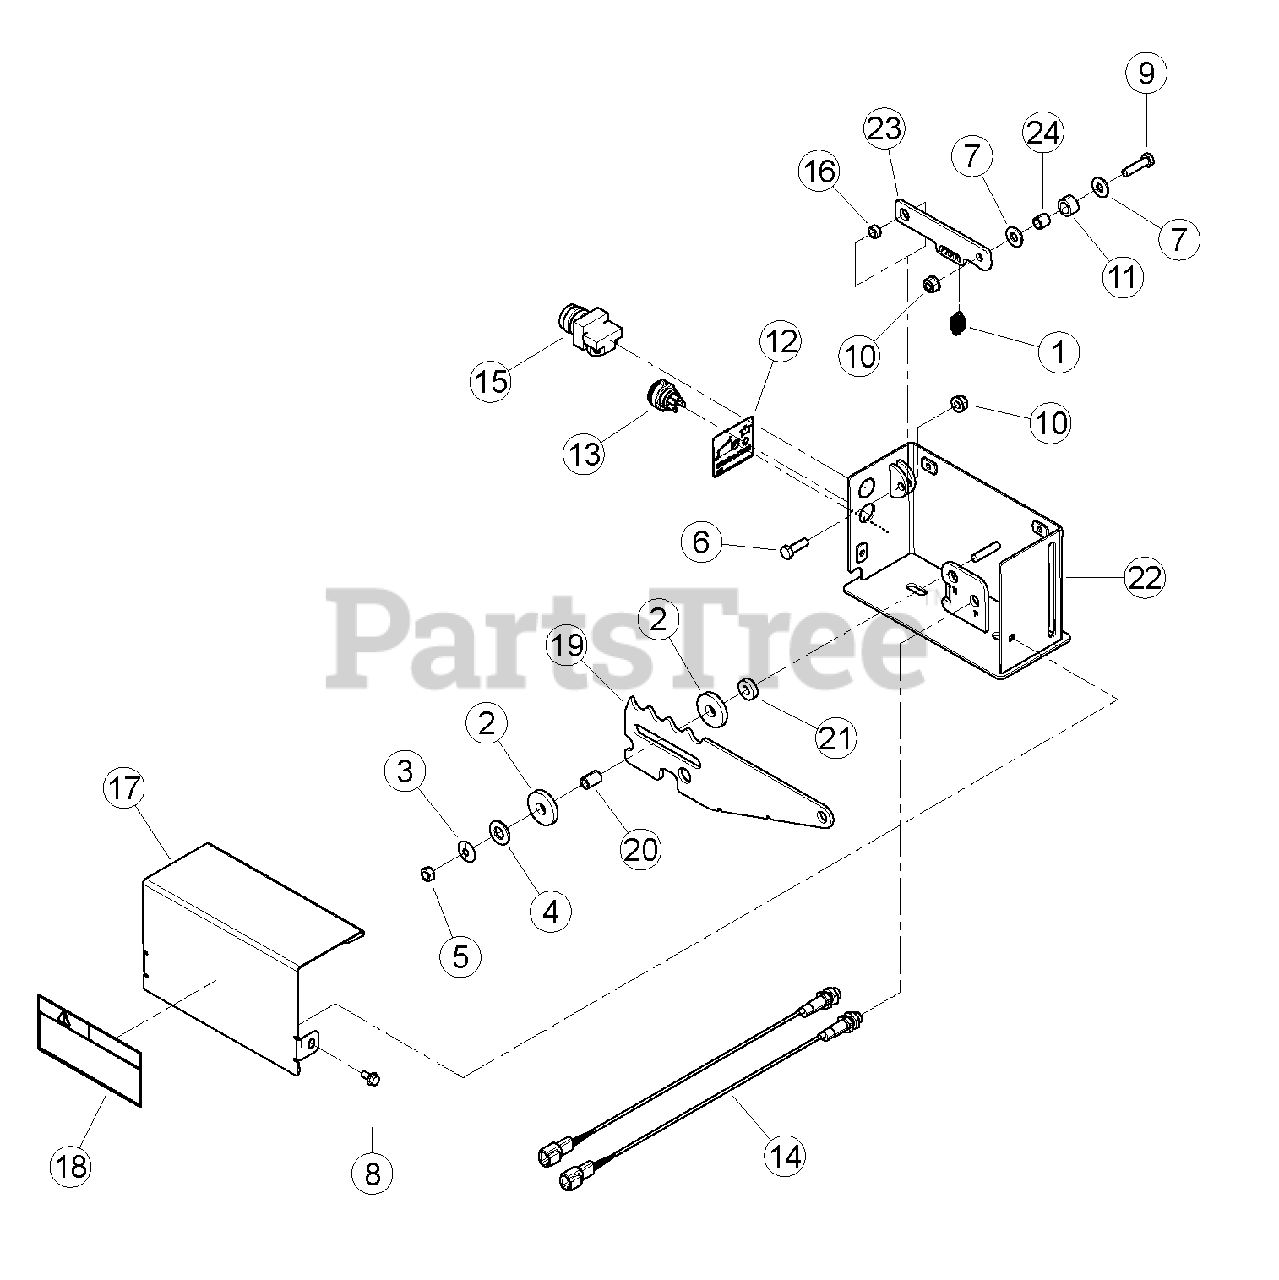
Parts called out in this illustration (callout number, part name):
1	SPRING, CONTROL BAR
2	WASHER, UHMW SPACER .515ID-1.50OD
3	WASHER, SPRING
4	WASHER, 1/2 SAE FLAT ZP
5	NUT, 5/16 CENTERLOCK NC ZP
6	BOLT, 5/16 X 1 HEX GR5 NC ZP
7	WASHER, 5/16 FLAT ZP
8	BOLT, 1/4 X 1/2 SERRATED FLANGE GR5 ZP
9	BOLT, 5/16 X 1-1/4 HEX GR5 NC ZP
10	NUT, 5/16-18 NYLOCK-FLANGE
11	ROLLER, NYLON .75OD X .502ID X .440
12	DECAL, RESET/OVERRIDE
13	LIGHT, LED TRI-COLOR
14	SENSOR, M12 PNP PROXIMITY (REPLACEMENT PART)
15	SWITCH, MOMENTARY IP65 NORMALLY OFF
16	SPACER, IDLER PIVOT
17	ASSEMBLY, CONTROL COVER W/ DECAL
18	DECAL, MULTILINGUAL MANUAL
19	BAR, SWITCH CONTROL
20	SPACER, .50 X .728"
21	SPACER, .375" X .25"
22	WELDMENT, SWITCH BOX
23	LINK, DETENT
24	SPACER, 1/2 OD X .35 ID X .47
